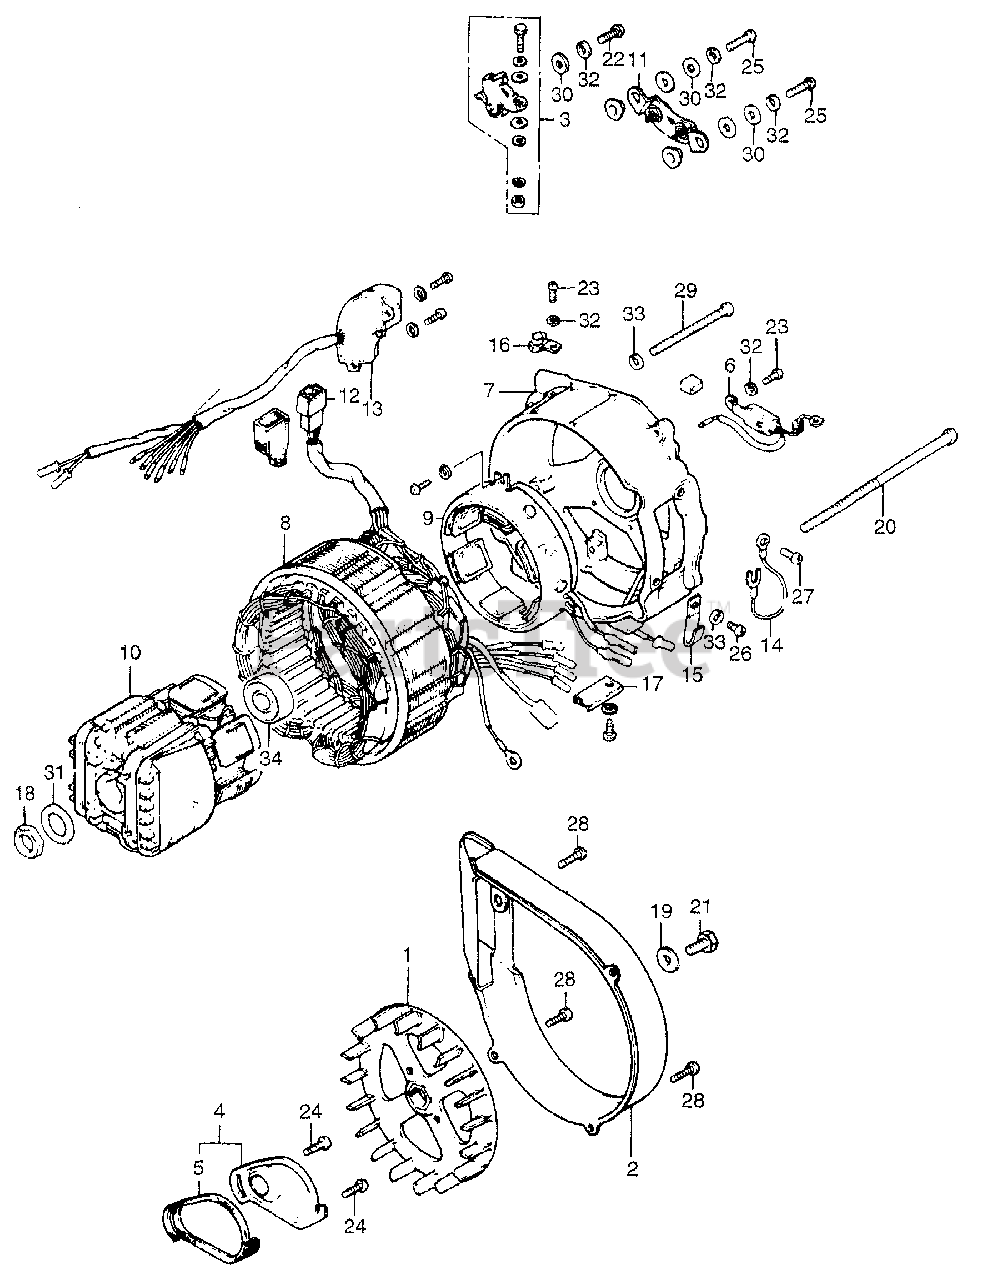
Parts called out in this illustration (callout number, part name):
1	FAN, ALTERNATOR COOLING (NOT AVAILABLE)
2	COVER, ALTERNATOR FAN
3	POINTS ASSY.
4	COVER ASSY., POINTS (NOT AVAILABLE)
5	GASKET, POINTS COVER (NOT AVAILABLE)
6	CONDENSER ASSY., IGNITION (NOT AVAILABLE)
7	BRACKET, RR.
8	STATOR ASSY.
9	STATOR ASSY., EXCITER (NOT AVAILABLE)
11	DIODE ASSY.
12	CONNECTOR (4P)
13	REGULATOR ASSY., AUTOMATIC VOL TAGE (NOT AVAILABLE)
14	WIRE, GROUND
15	CLAMP A, WIRE (NOT AVAILABLE)
16	CLAMP, WIRE
17	CLAMP, WIRE
18	NUT, SPECIAL (14MM)
19	WASHER (6X17)
20	BOLT, ALTERNATOR SET (NOT AVAILABLE)
21	BOLT, HEX. (6X14)
22	SCREW, PAN (4X6)
23	SCREW, PAN (4X8)
24	SCREW, PAN (4X12)
25	SCREW, PAN (4X14)
26	SCREW, PAN (5X8)
27	SCREW, PAN (5X8)
28	SCREW, PAN (5X10)
29	SCREW, PAN (5X55) (NOT AVAILABLE)
30	WASHER, PLAIN (4MM)
31	WASHER, PLAIN (14MM)
32	WASHER, SPRING (4MM)
33	WASHER, SPRING (5MM)
34	BEARING, RADIAL BALL (6001UU)
